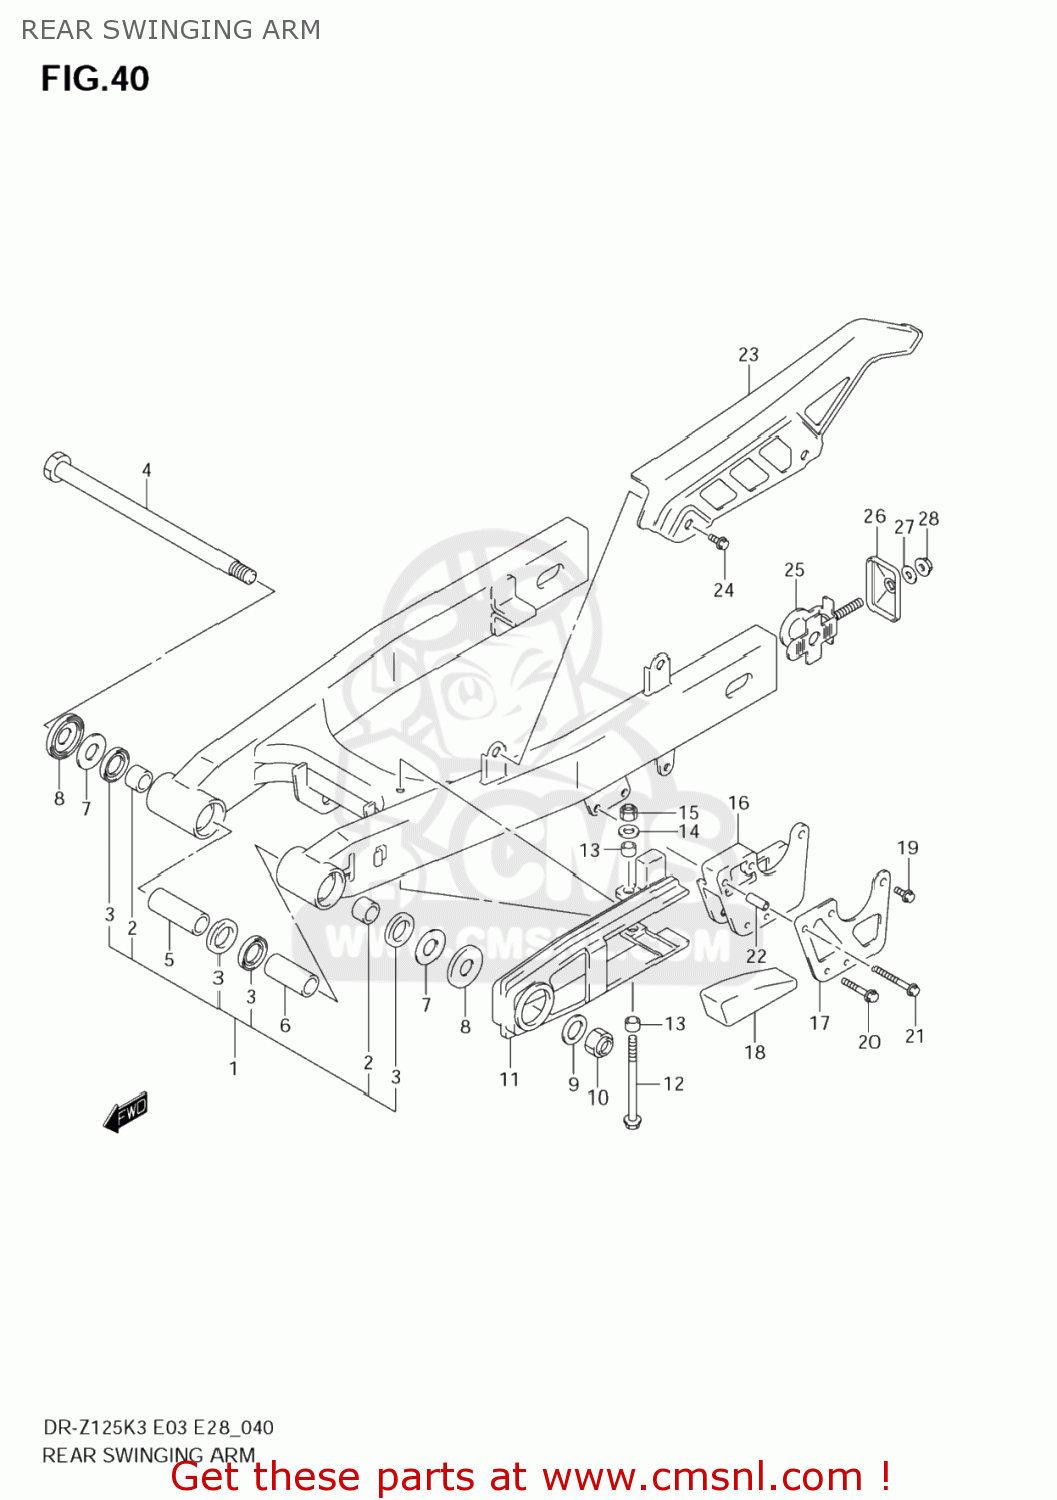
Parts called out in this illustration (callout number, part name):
1	SWINGINGARM ASSY,RR
2	BUSHING,RR SWGARM PIVOT
3	SEAL,OIL(20X27X5)
4	SHAFT,RR SWINGINGARM PIVOT
5	SPACER,RR SWGARM PIVOT,R
6	SPACER,RR SWGARM PVT
7	WASHER
8	COVER,RR SWGARM DUST SEAL
9	WASHER(14.5X24X2.3)
10	NUT
11	BUFFER,CHAIN TOUCH DEFENSE
12	BOLT
13	SPACER(6.5X9X6.5)
14	WASHER
15	NUT
16	GUIDE,CHAIN
17	PLATE,GUIDE CHAIN OUTER
18	DEFENSE,CHAIN GUIDE
19	BOLT(6X16)
20	BOLT(6X40)
21	BOLT(6X30)
22	SPACER(6.5X10X23.5)
23	CASE,CHAIN
24	BOLT(6X10)
25	ADJUSTER,CHAIN
26	PLATE,CHAIN ADJUSTER
27	WASHER(12.5X26X2.3)
28	NUT
